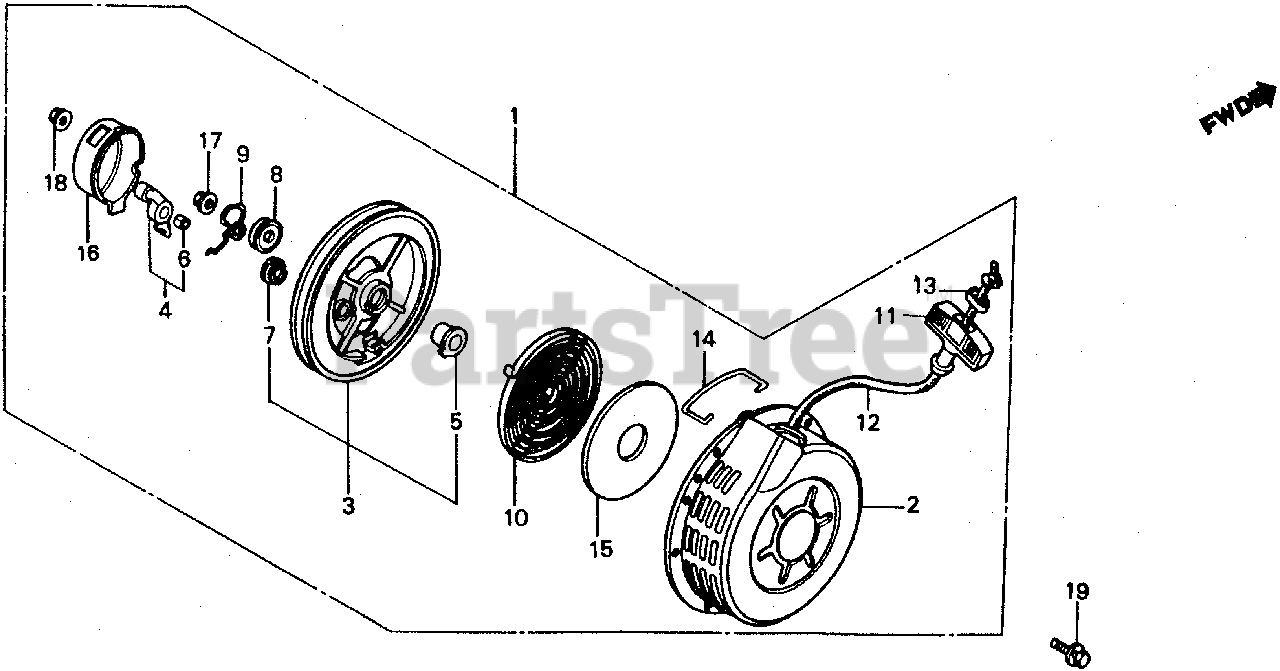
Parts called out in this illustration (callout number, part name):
1	STARTER ASSY., RECOIL *R8* (BRIGHT RED)
2	CASE, STARTER *R8* (BRIGHT RED)
3	REEL, STARTER
5	BOSS, REEL
6	BUSH, RATCHET
7	BUSH, REEL STARTER
8	PLATE, FRICTION
9	SPRING, FRICTION
10	SPRING, RETURN
11	GRIP, STARTER
12	ROPE, STARTER (#6X64")
13	SUPPORT, GRIP
14	HOLDER, ROPE
15	PLATE, SIDE
16	COVER, REEL STARTER
17	NUT, SELF-LOCK (8MM)
18	NUT, SELF-LOCK (6MM)
19	BOLT-WASHER (6X10)
